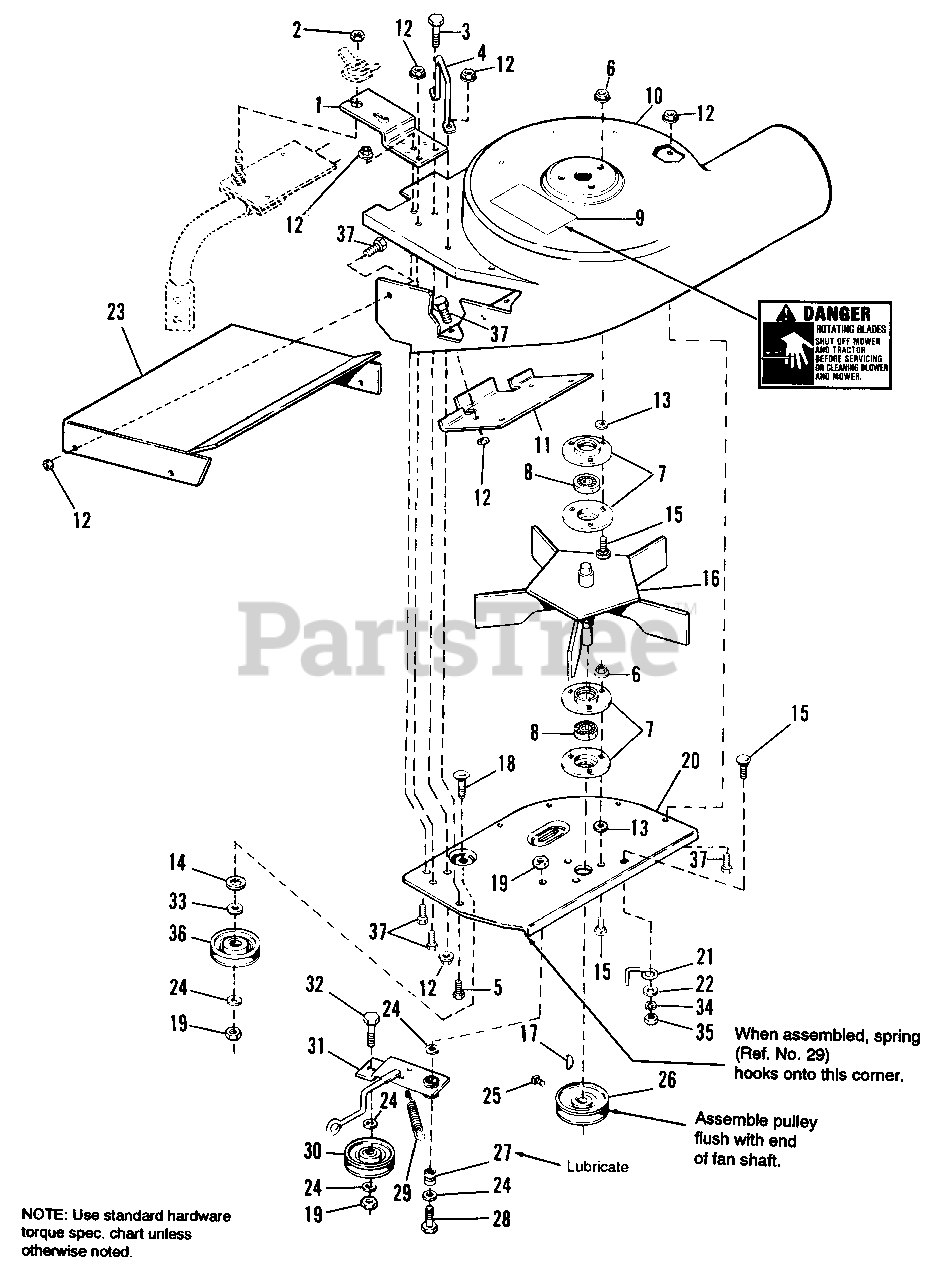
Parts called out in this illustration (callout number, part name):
1	MOUNTING PLATE
2	CAPSCREW, Hex Hd., 1/4-20 x 3/4
3	CAPSCREW, Hex Hd., Full Thread, 1/4-20 x 2-1/4
4	STOP, Deflector
5	CAPSCREW, Hex Hd., 1/4-20 x 7/8
6	NUT, Flange Lock, 5/16-18
7	RETAINER, Bearing
9	DECAL, Warning
10	TURBO HOUSING (Incl. Ref. No. 29)
11	HOOK, Stoneguard
12	NUT, Hex, Flange Whiz, 1/4-20
13	PUSHNUT, 5/16
14	WASHER, Plain, 1/2
15	CARRIAGE BOLT, 5/16-18 x 3/4
16	FAN ASSY., 5-Blade
17	KEY, Modified
18	CARRIAGE BOLT, 3/8-16 x 1-1/4
19	LOCKNUT, Jam, 3/8-16
20	PLATE, Shroud
22	WASHER, 11/32
23	COVER, Top
24	WASHER, 13/32
25	SETSCREW, Socket Hd., 5/16-18 x 5/16
26	PULLEY, Driven
27	SPACER
28	CAPSCREW, Hex, 3/8-16 x 1-1/2
30	PULLEY, "V"
31	IDLER ARM ASSY.
32	CAPSCREW, Hex, 3/8-16 x 1
33	WASHER, Special
34	LOCKWASHER
35	NUT, 5/16
36	PULLEY, Idler
37	CAPSCREW, Hex Hd., 1/4-20 x 5/8
